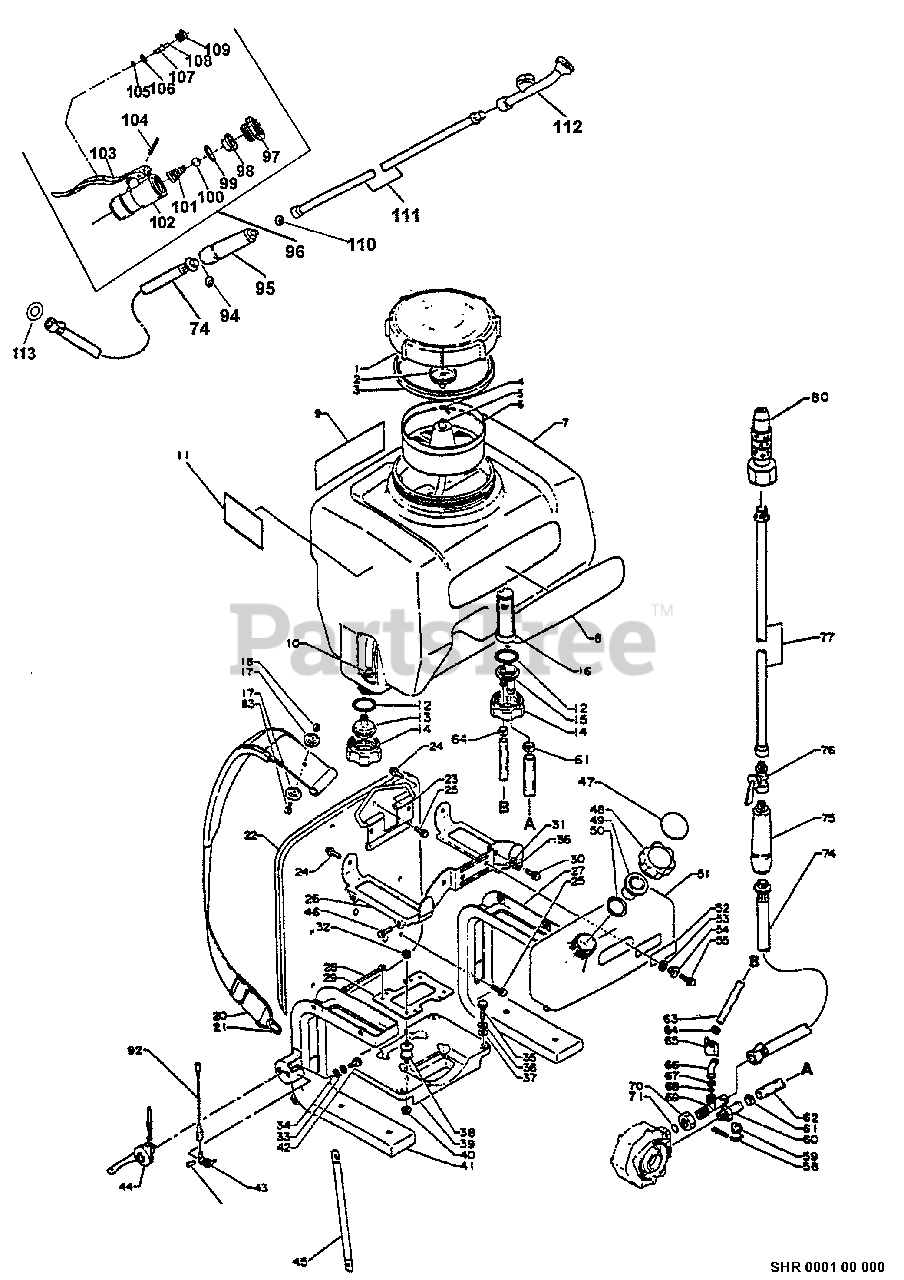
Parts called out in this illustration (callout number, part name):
1	CAP, CHEMICAL TANK
2	VENT, TANK
3	GASKET, CAP
4	CLAMP
5	HOSE, AIR
6	FILTER, CHEMICAL TANK
7	TANK, CHEMICAL
9	LABEL - CAUTION
10	CLAMP
11	LABEL - CAUTION
12	O-RING - 28
13	BREATHER
14	NUT - PLASTIC
18	LOCKNUT - 5
20	BACKPACK STRAP ASSY
21	RING, STRAP
23	ARM
24	SCREW - 6X10
25	SCREW - 5X10
26	BRACKET
27	FRAME, BACKPACK - RIGHT
28	LEAD - GROUND
29	PLATE, CUSHION
30	SCREW - 6X10
31	WASHER - 6
32	NUT - 5 -- FLANGE
33	LOCKWASHER - 5
34	WASHER - 5
35	BOLT - 6X20
36	LOCKWASHER - 6
37	WASHER - 6
39	BRACKET, ENGINE
40	NUT - 5 -- FLANGE
41	FRAME, BACKPACK - LEFT
42	BOLT - 5X12
43	IGNITION SWITCH ASSY
44	LEVER, THROTTLE
45	BAR
46	SCREW - 6X14
47	LABEL - FUEL MIX
48	CAP ASSY
49	VENT, CAP
50	GASKET, CAP
51	TANK, FUEL
52	LABEL - MODEL
53	WASHER - RUBBER
54	SPACER
55	SCREW - 6X20
58	DRAIN PLUG KIT
60	JOINT, INLET
62	HOSE, INLET
63	HOSE, BYPASS
65	WINGNUT
66	JOINT, BYPASS
67	GASKET, BYPASS NOZZLE
69	JOINT, OUTLET
71	O-RING - 10
74	HOSE, SPRAY
75	GRIP
76	VALVE, NOZZLE
77	TUBE, NOZZLE
83	SCREW - 5X14
91	LABEL - STOP
92	LEAD - GROUND
94	GASKET
95	GRIP
96	VALVE ASSY
100	VALVE, BALL - 5X16
102	VALVE, NOZZLE
104	PIN - SPRING -- 3X16
106	RING, RETAINING - 2
107	PIN
109	O-RING - 3
110	GASKET
111	TUBE, NOZZLE
112	NOZZLE, 2-HEAD
113	GASKET, BYPASS NOZZLE
